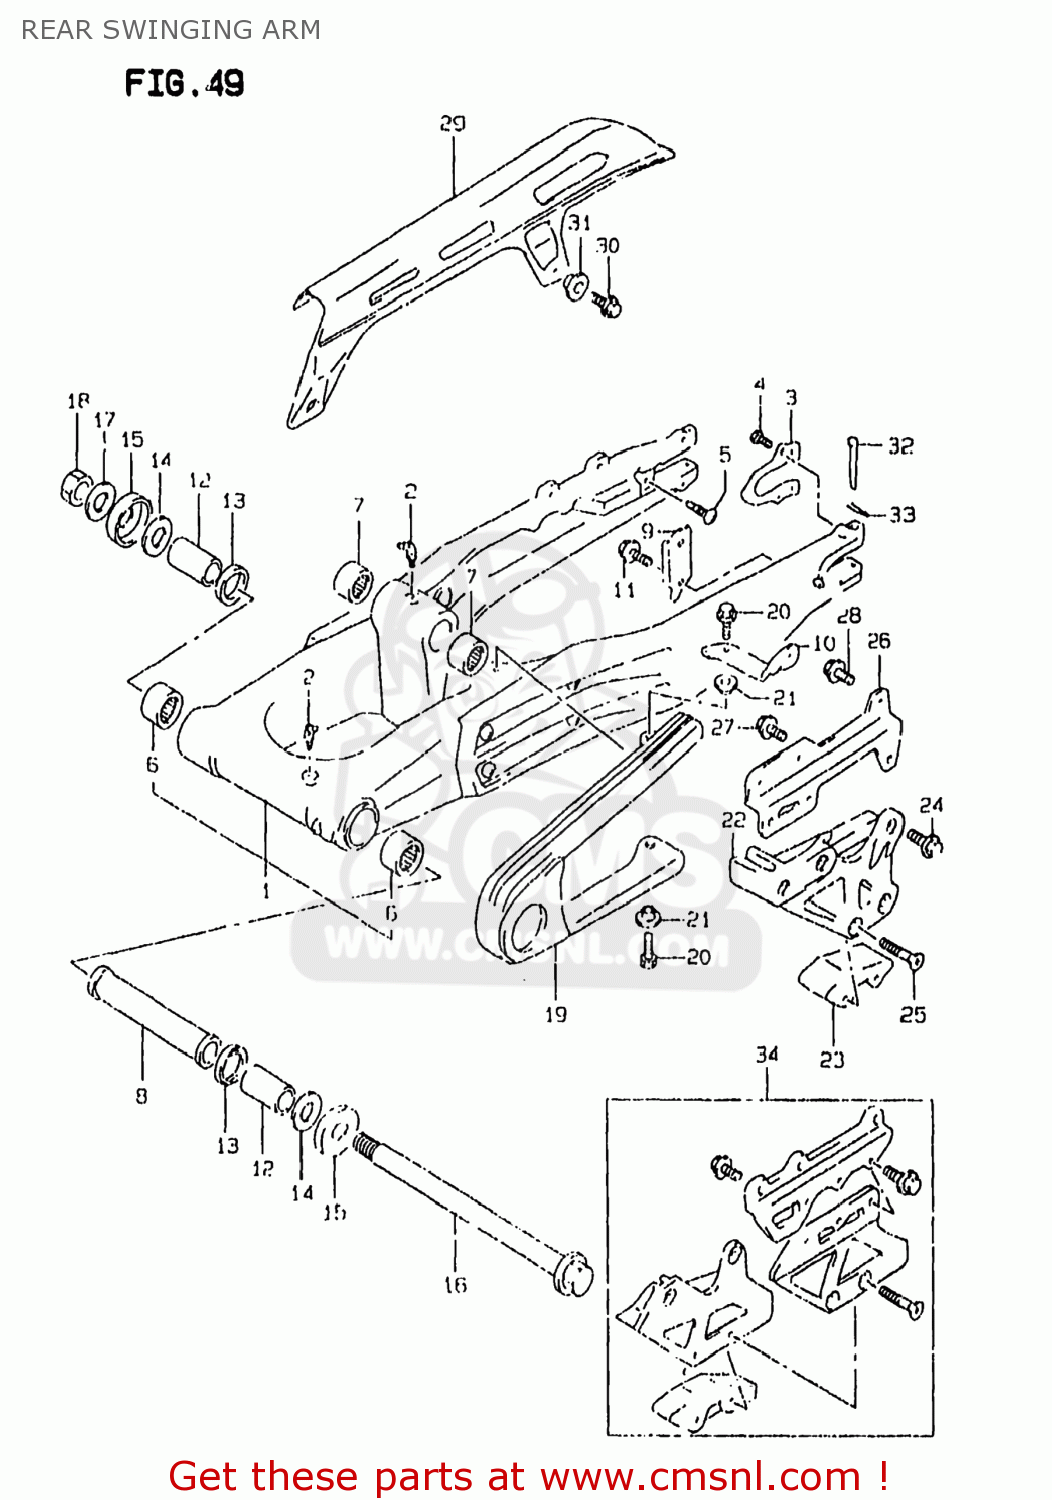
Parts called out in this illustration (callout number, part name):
1	SWINGINGARM ASSY,RR
2	NIPPLE,GREASE
3	PLATE,SWING ARM RR
4	SCREW (5X8)
5	SCREW (M10X21)
6	BEARING(22X29X30)
7	BEARING(20X27X23.5)
8	SPACER,SWING ARM PIVOT,CENTER
9	PLATE,CHAIN CASE FTG RR
10	PLATE,CHAIN CASE FTG FR
11	BOLT
12	SPACER,SWGARM PIVOT BRG
13	SEAL,OIL(22X29X4)
14	WASHER
15	COVER,SWINGINGARM PIVOT
16	SHAFT,SWINGING ARM PIVOT
17	WASHER, FIXED DRIVE FACE
18	NUT
19	BUFFER,CHAIN TOUCH DEFENSE
20	BOLT
21	WASHER
22	GUIDE,CHAIN
23	DEFENSE,CHAIN GUIDE
24	BOLT
25	SCREW
26	BRACKET,CHAIN GUIDE
27	BOLT
28	BOLT
29	CASE,CHAIN
30	BOLT
31	WASHER
32	PIN
33	CLIP
34	GUIDE SET,CHAIN
